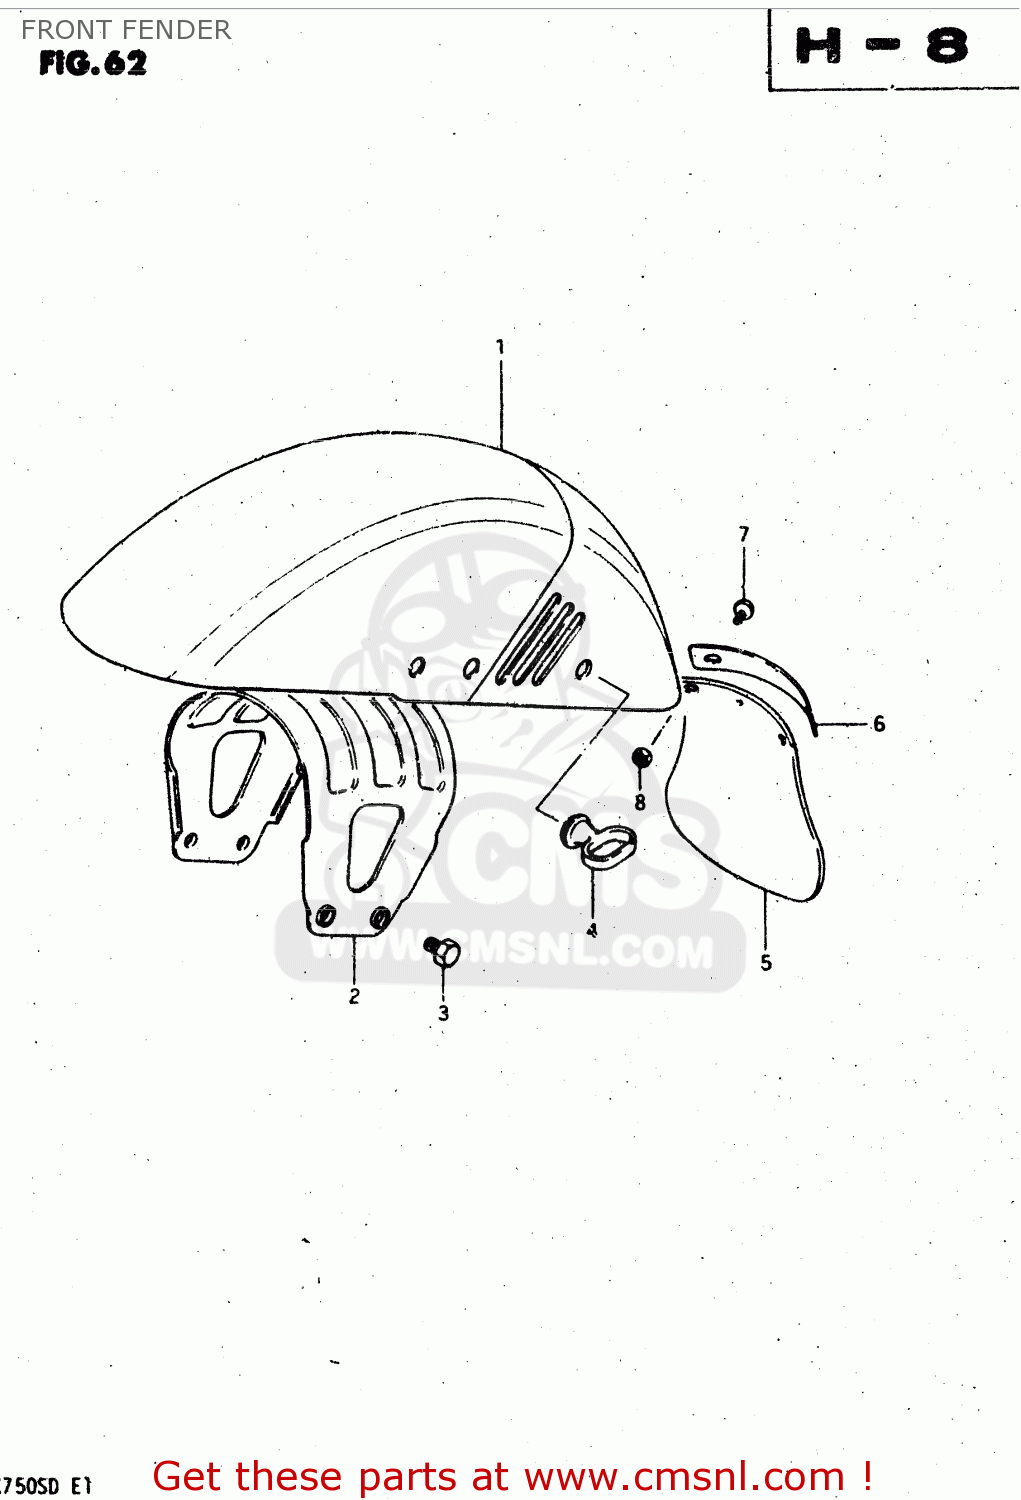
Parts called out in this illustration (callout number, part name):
1	FENDER, FRONT (RED)
2	BRACE,FR FENDER CTR
3	BOLT 8X16
4	GUIDE,CABLE
5	FLAP,MUD
6	PLATE
7	SCREW
8	NUT 5MM
